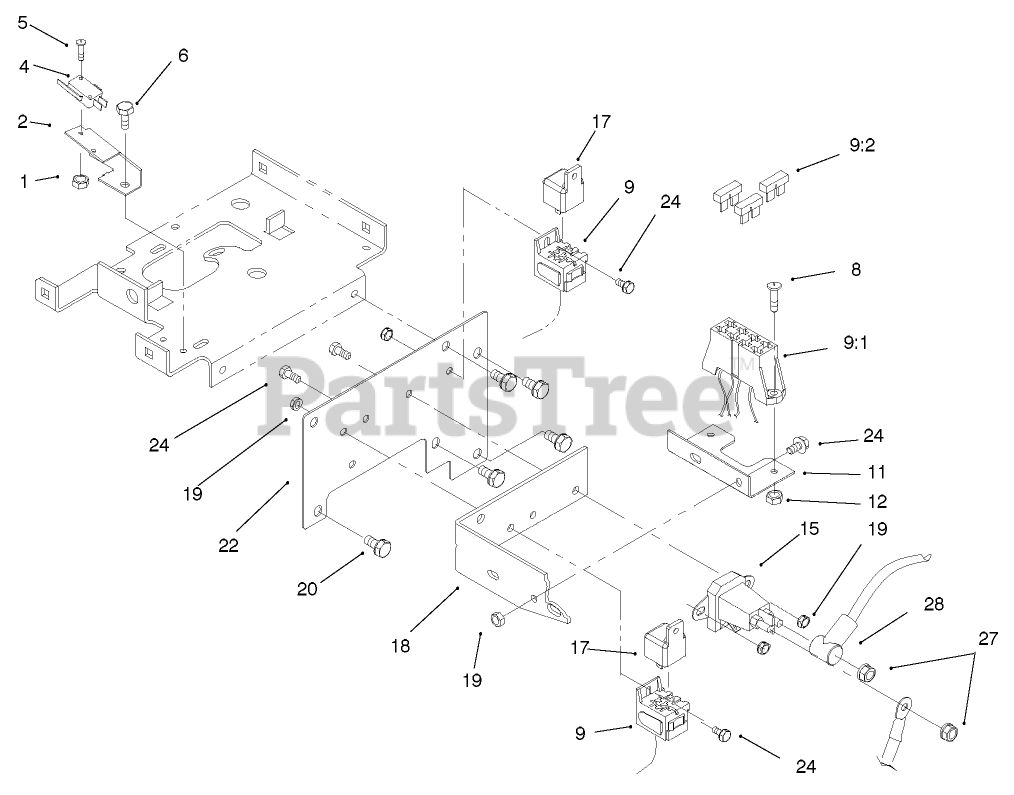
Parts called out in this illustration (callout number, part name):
1	NUT-HEX, NYL INS
4	SWITCH
5	SCREW-PPH
6	SCREW-HWH
8	SCREW-PAN
9	HARNESS - WIRE, MAIN
9:2	FUSE-BLADE, 25 AMP
9:2	FUSE-BLADE, 20 AMP
9:2	FUSE-30 AMP
11	FUSE HOLDER
17	RELAY
18	BRACKET-BELT
19	NUT-LOCK, NI
22	PLATE-FRONT HOODS
23	CABLE
24	SCREW-HHF
27	NUT-KEPS
